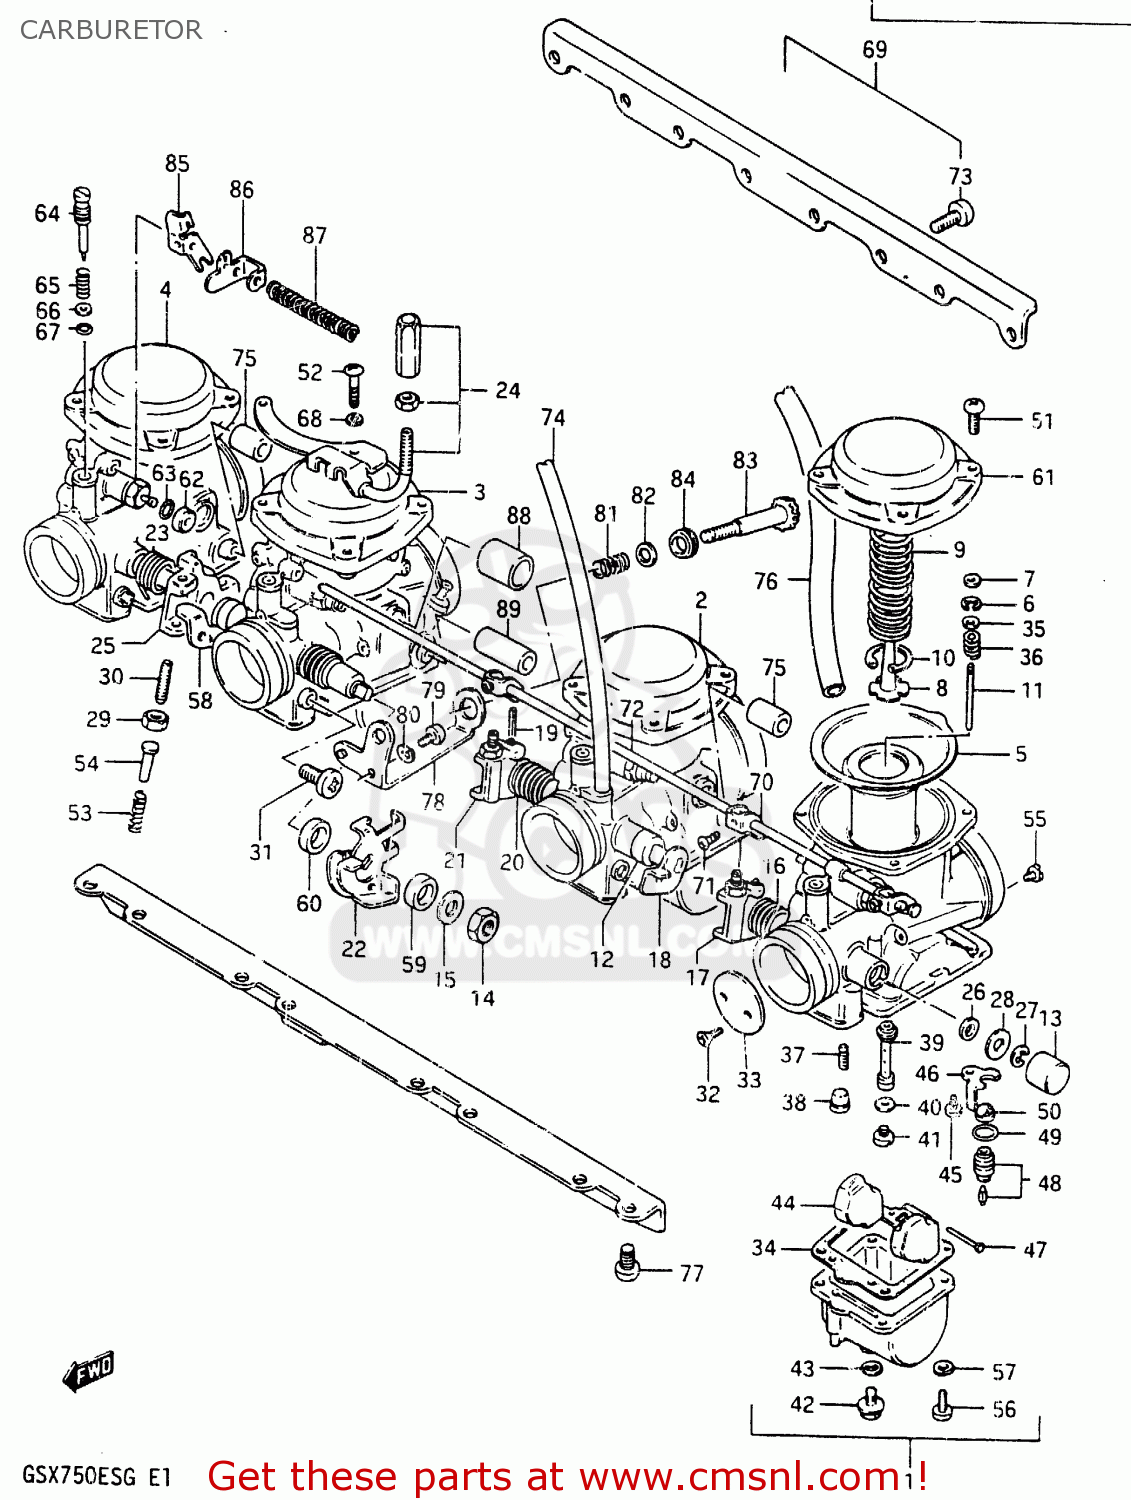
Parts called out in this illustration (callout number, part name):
1	CARBURETOR, LH
2	CARBURETOR, ML
3	CARBURETOR, MR
4	CARBURETOR, RH
5	DIAPHRAGM,CARBURETOR
6	CLIP,NEEDLE
7	RING
8	HOLDER,GUIDE
9	SPRING,DIAPHRAGM
10	E RING
11	NEEDLE,JET
12	GASKET
13	CAP
14	NUT
15	WASHER
16	SPRING,THROTTLE SHAFT
17	SHAFT,THROTTLE
18	SHAFT,THROTTLE
19	PIN,THROTTLE SHAFT
20	SPRING,THROTTLE SHAFT
21	LEVER,THROTTLE SHAFT
22	LEVER ASSEMBLY,THROTTLE
23	SPRING,THROTTLE SHAFT
24	BRACKET,THROTTLE CABLE
25	SHAFT,THROTTLE
26	SEAL
27	E RING
28	GASKET,THROTTLE SHAFT (NAS)
29	NUT
30	SCREW
31	SCREW
32	SCREW
33	VALVE,THROTTLE (BUTTERFLY)
34	GASKET,FLOAT CHAMBER (NAS)
35	WASHER
36	SPRING
37	JET(40)
38	PLUG,NEEDLE JET
39	JET,NEEDLE(Y-7)
40	WASHER,NEEDLE NOZZLE
41	JET
42	PLUG,DRAIN
43	GASKET (NAS)
44	FLOAT
45	SCREW
46	PLATE,NEEDLE VALVE FITING
47	PIN,FLOAT
48	VALVE ASSEMBLY,NEEDLE
49	O-RING,NEEDLE VALVE
50	FILTER
51	SCREW
52	SCREW
53	SPRING,THROTTLE SCREW
54	PIN,THROTTLE LEVER
55	JET,AIR
56	SCREW
57	LOCK WASHER
58	SHAFT,THROTTLE
59	RING
60	RING
61	COVER
62	CAP,STARTER VALVE
63	O RING
64	SCREW,PILOT AIR
65	SPRING
66	GASKET
67	O-RING
68	LOCK WASHER
69	FLANGE ASSEMBLY,CARBURETOR
70	LEVER
71	SCREW,THROTTLE ADJUST
72	SHAFT,STARTER
73	SCREW 5X12
74	HOSE 4.5X8X390
75	NIPPLE,CARBURETOR
76	HOSE
77	SCREW
78	BRACKET,THROTTLE ADJUST
79	SCREW 5X10
80	LOCK WASHER
81	SPRING
82	WASHER
83	ADJUSTER
84	BUSH
85	LEVER,CHOKE CABLE
86	PLATE,CHOKE CABLE
87	SPRING,CHOKE CABLE
88	HOSE
89	NIPPLE,CARBURETOR
